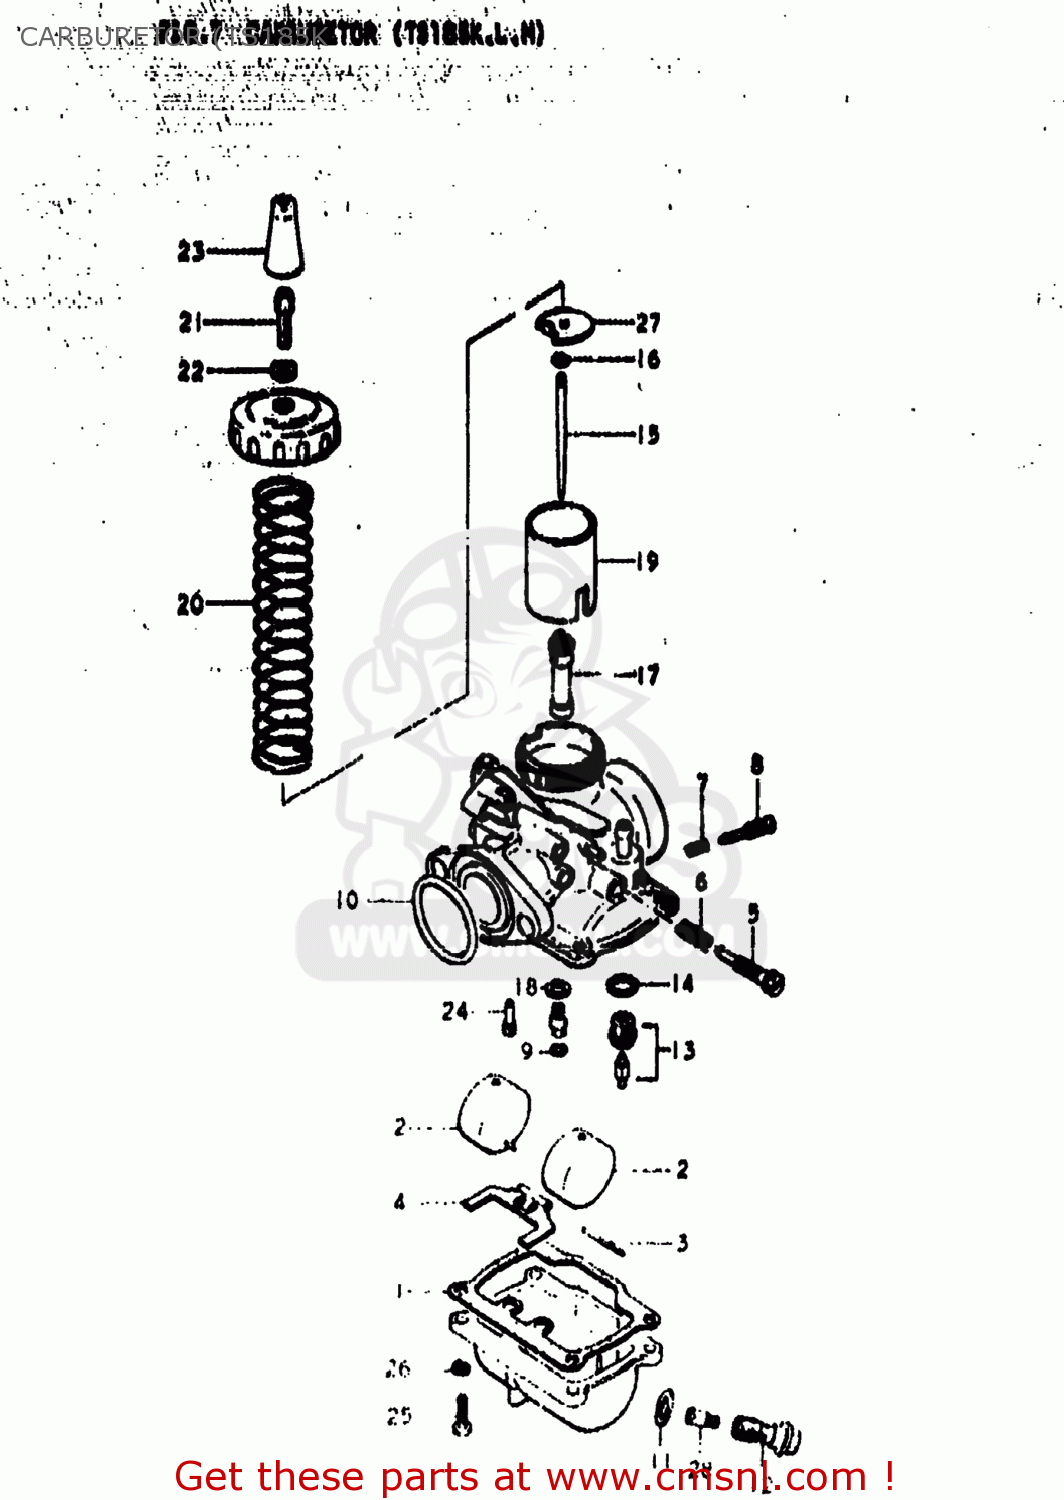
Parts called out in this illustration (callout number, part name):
0	CARBURETOR ASSEMBLY
1	GASKET,FLOAT CHAMBER (NAS)
2	FLOAT
3	PIN,FLOAT
4	ARM,FLOAT
5	ADJUSTER
6	SPRING,THROTTLE SCREW
7	SPRING
8	SCREW,PILOT AIR
9	O RING
10	O RING
11	WASHER
13	VALVE ASSEMBLY,NEEDLE
14	GASKET,VALVE SEAT (NAS)
15	NEEDLE JET
16	CLIP
17	JET,NEEDLE
18	WASHER
19	VALVE,THROTTLE
20	SPRING, THROTTLE VALVE
21	ADJUSTER,CABLE
22	NUT
23	CAP
24	JET
25	SCREW
26	LOCK WASHER
27	SEAT,THROTTLE VALVE SPRING
28	JET
